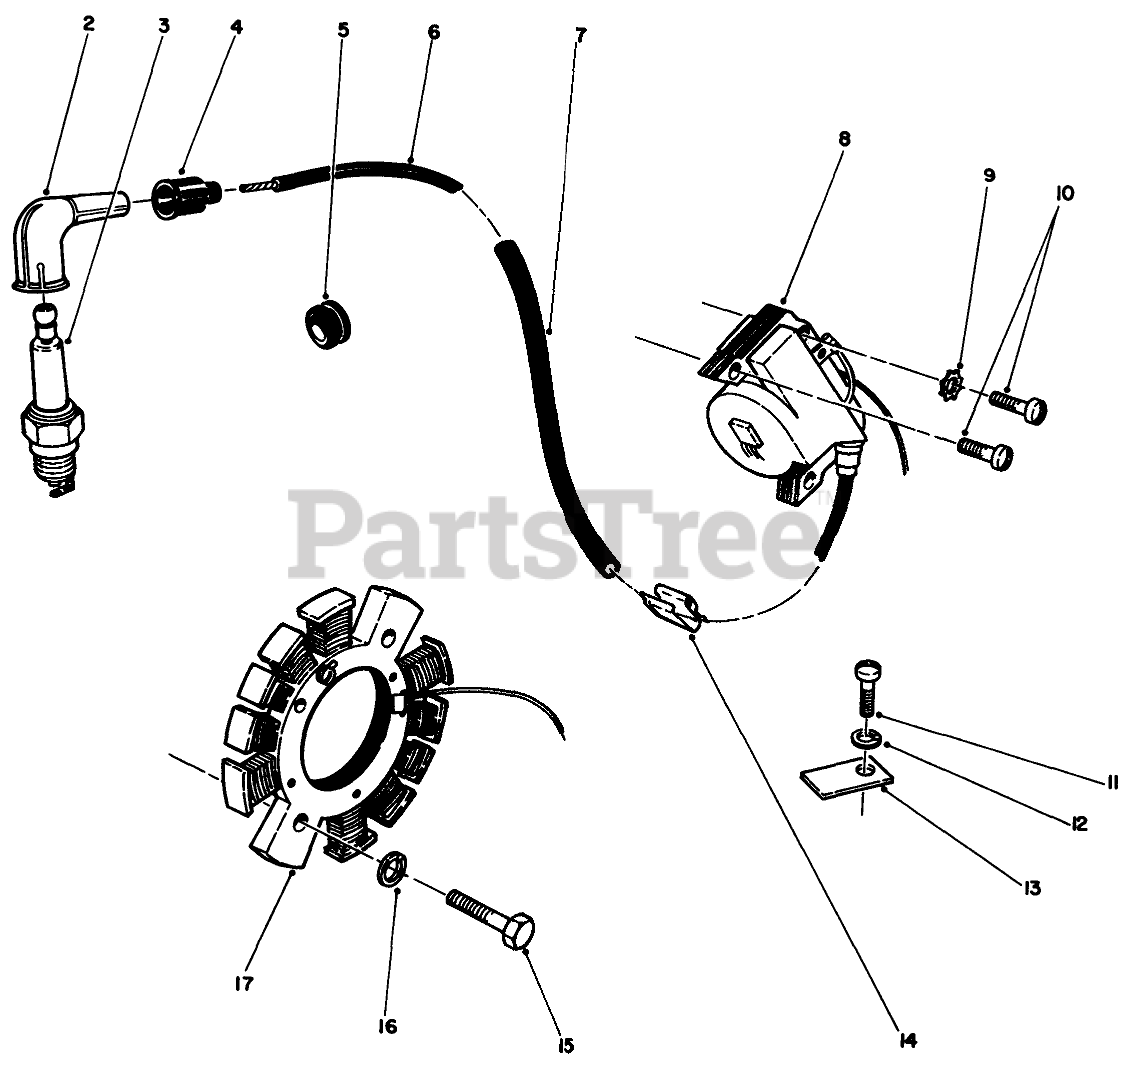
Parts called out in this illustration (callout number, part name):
2	SPARK PLUG CAP
3	Spark Plug
4	Rubber Socket
5	Grommet
6	Spark Plug Wire
7	Hose-Protection
8	lgnition Module
9	Lockwasher Ext. Tooth
10	Capscrew
11	Capscrew
12	Lockwasher
13	Support
14	Clamp
15	Capscrew-Hex Head
16	Lockwasher
17	GENERATOR
